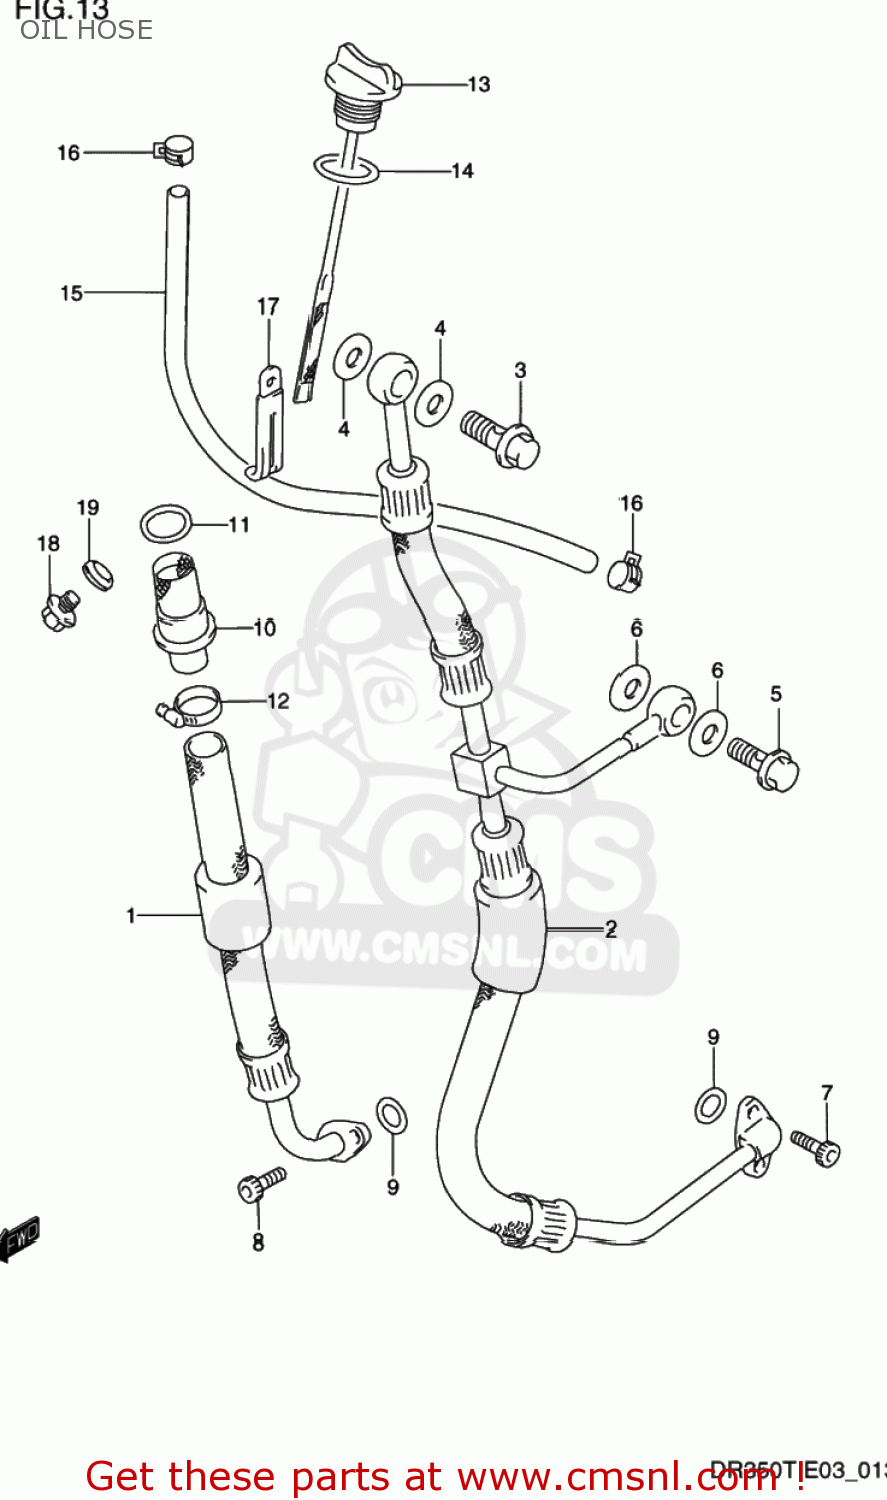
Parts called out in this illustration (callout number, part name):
1	HOSE,OIL
2	HOSE,OIL
3	BOLT UNION
4	GASKET(16X22X2) (NAS)
5	BOLT UNION
6	GASKET(12X17X1) (NAS)
7	BOLT
8	BOLT
9	O RING(D:2.4,ID:12.3)
10	STRAINER,FRAME HEAD UNDER
11	O RING(D:3.1,ID:22.7)
12	CLAMP
13	GAUGE ASSY,OIL LEVEL
14	O RING(D:3.1,ID:16.8)
15	HOSE,OIL OVER FLOW
16	CLIP
17	CLAMP
18	PLUG
19	GASKET(10X14X3.6) (NAS)
